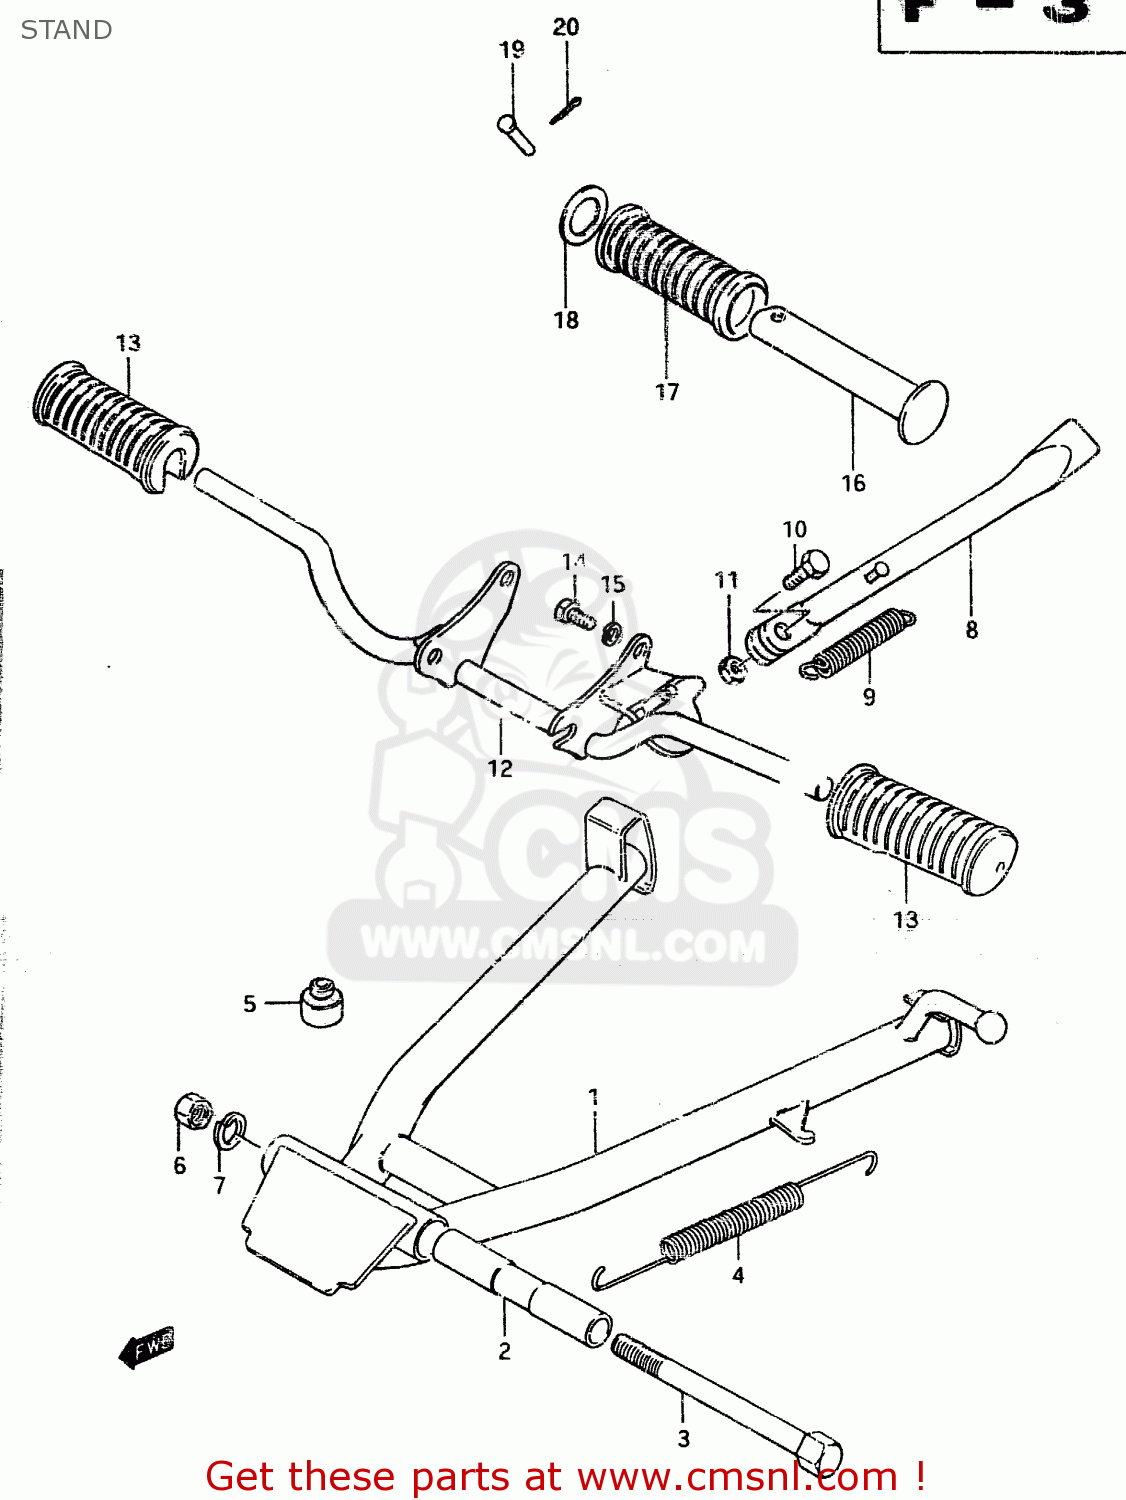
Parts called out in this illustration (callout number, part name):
1	STAND, CENTER
2	SPACER
3	BOLT(10X110)
4	SPRING
5	CUSHION
6	NUT
7	LOCK WASHER
8	STAND, PROP
9	SPRING
10	BOLT
11	NUT
12	BAR, FRONT FOOTREST
13	RUBBER,FR FOOTREST
14	BOLT
15	LOCK WASHER
16	BAR,FOOTREST RUBBER
17	RUBBER,PILLION FOOTREST
18	WASHER (19.5X32X2)
19	PIN
20	PIN 20X20
